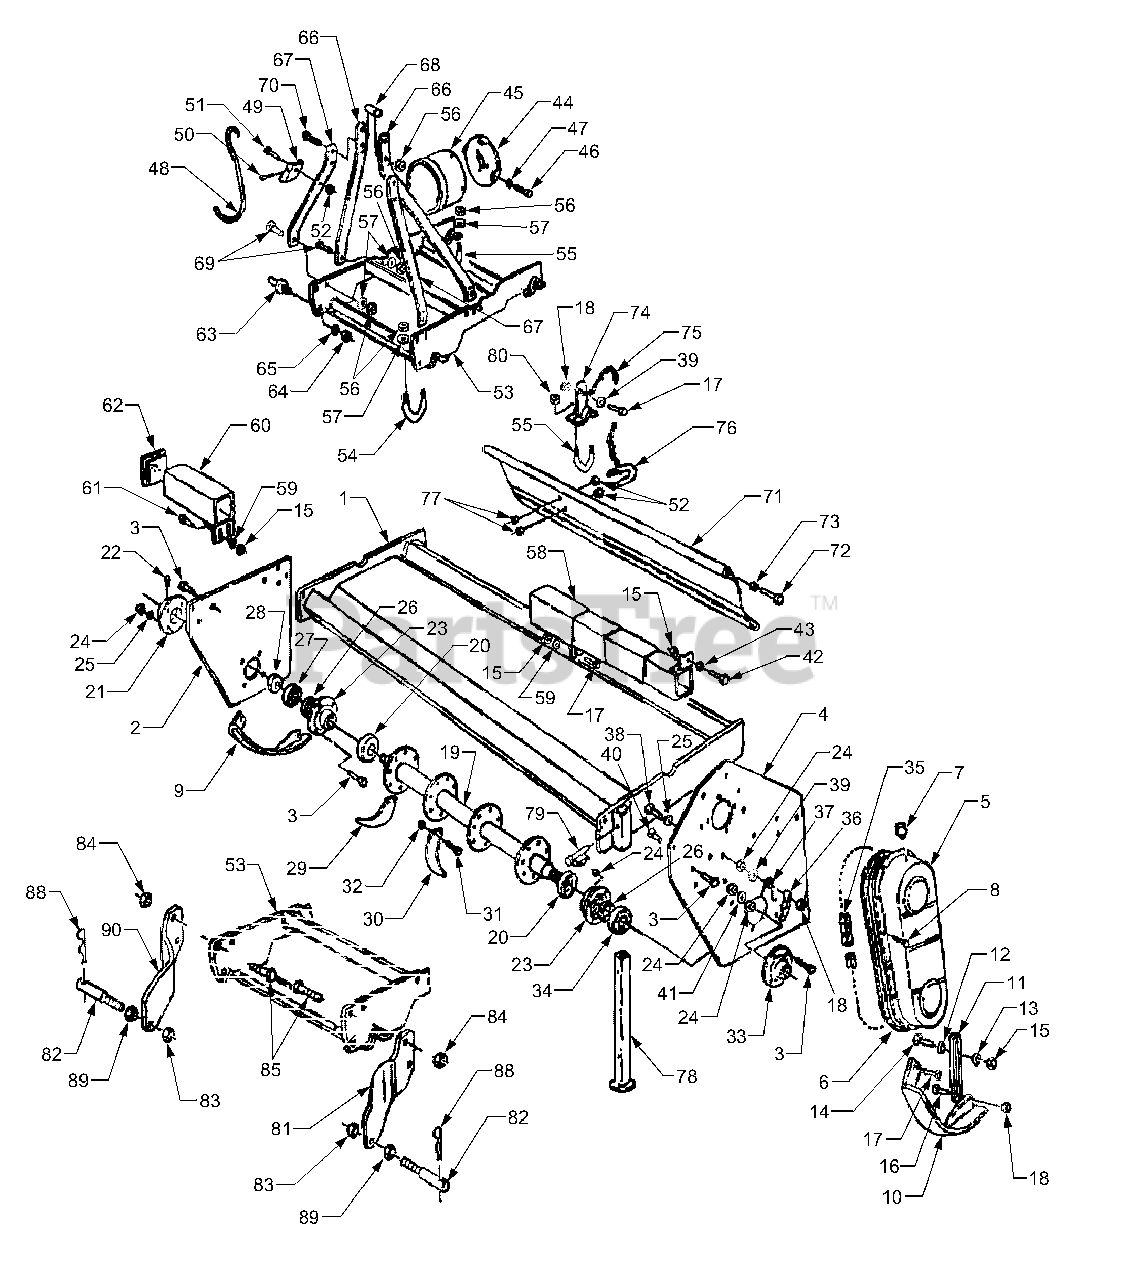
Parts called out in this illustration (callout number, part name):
2	Right Side Panel
4	Drive Panel
5	Chain Case Cover
7	Breather Cap
9	Skid - Right
10	Skid - Left
11	Adjustment Arm
12	Threaded Washer
20	Dirt Shield
21	Outer Cover - Right
22	Grease Fitting
28	Safety Nut M30x1.5
29	C-Blade - Right
30	C-Blade - Left
33	Outer Cover Left
35	Chain ASA 60x46 (540 rpm)
36	Chain Tensioner
39	Flat Washer M10
41	Flat Washer M10
44	Protection Support
45	PTO Shaft Protection
47	Flat Washer M6
48	Driveline Hook
49	Hook Support
50	Cotter Pin D.2
53	Side Shift 3rd Point Hitch
56	Nut M12
58	Protection 50"
59	Washer M10x4
60	Right Protection 50"
62	Plastic Cap
66	Top Hitch Arm
67	Top Hitch Support
70	Bolt 12x110
71	Tail Gate 50"
74	Chain Hitch
79	Cotter Pin 10x70
82	Lower Hitch
88	Safety Clips
90	Right Plate
